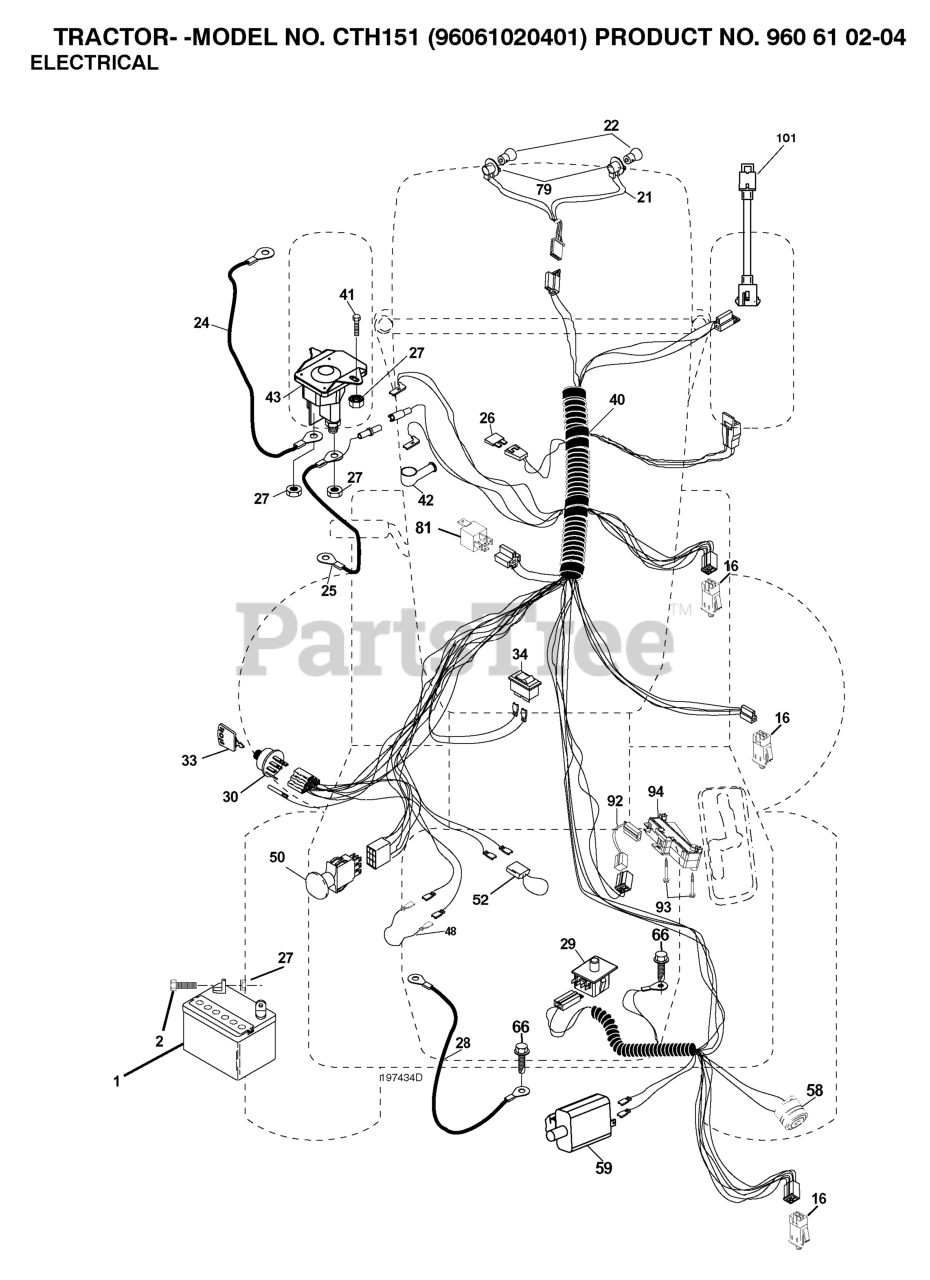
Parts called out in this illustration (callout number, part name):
1	BATTERY 12V .35 AMP
2	BOLT.HEX.1/4.X.3/4.DICHROMATE
16	SWITCH INTERLOOK PUSH-IN
21	HARNESS.LIGHT W/4152J BULBS
24	BATTERY CABLE GT
25	CABLE BATTERY
26	FUSE 20AMP
27	NUT
28	CABLE GROUND
29	SWITCH.SEAT.DP W/RAMPS
30	SWITCH.IGN.DELTA.W.LGH.ROS
33	KEY MLD GEN DELTA
40	RP HARNESS.IGN.ELECT.REG.CRD
41	BOLT
42	TERMINAL COVER
43	SOLENOID.W/BRASS.PLUNGER
48	ADAPTER.AMMETER
50	RP.PTO.SWITCH.8 TERMINAL.BLACK
52	WIRE PROTECTION LOOP
58	BUZZER
59	.WITCH.FULL BAGGER.INDICATOR
79	BULB HOLDER ASM.
81	RELAY.ASSY.T
92	HARNESS.PIGTAIL.CONSLE
93	SCREW.PLASTITE
94	MODULE.REVERSE.ROS
101	PIGTAIL.MATNLK.NEW.HAR
